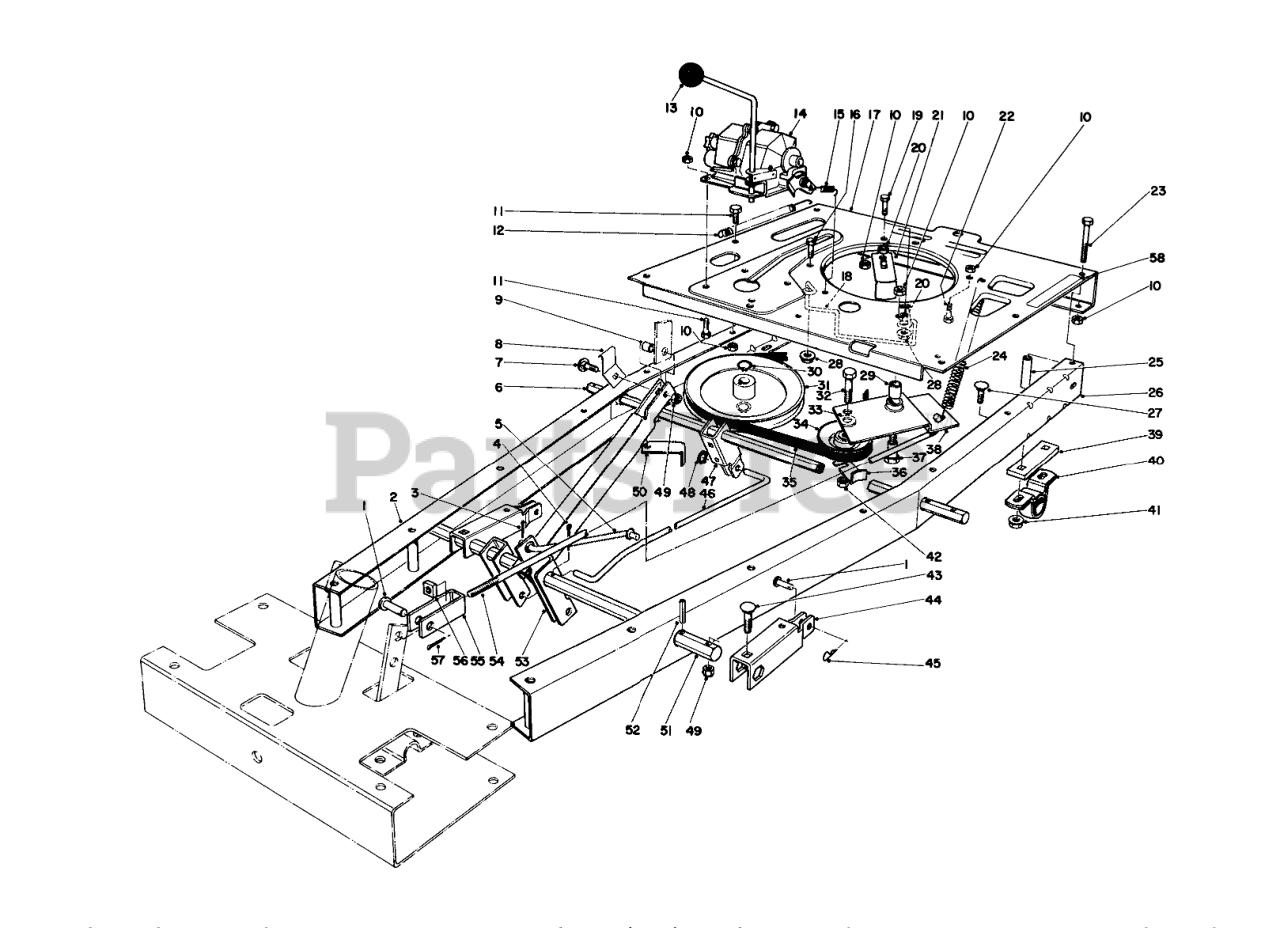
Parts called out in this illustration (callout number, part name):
1	PIN-CLEVIS
2	Frame Channel R.H.
3	PIN-COTTER
3	Cotter Pin
4	PIN-COTTER
5	Deck Engagement Rod
6	Hex Shaft-Rear Lift
7	SCREW-CARR
8	Flat Spring
9	Spacer
10	NUT-LOCK, CONE
11	SCREW-HH
12	Spring Tension Brake
13	KNOB-CONTROL
14	Transmission
15	Spring Tension Brake Return
16	SCREW-HH
17	Plate-Engine Mounting
18	Belt Guide
19	SCREW-HH
19	NUT-HEX
20	NUT-HEX
20	Belt Retainer
21	Belt Retainer
21	SCREW-HH
22	SCREW-HH
22	Spacer
23	SCREW-HH
24	SPRING-EXTENSION
25	Spacer-Split Tube
26	Channel Frame L.H.
27	BOLT-CARR
28	NUT-HF
29	BUSHING
30	RING-SNAP, EXTERNAL
31	Pulley
32	SCREW-HH
33	Washer
34	PULLEY-IDLER
35	TRACT DRIVE V-BELT
36	RETAINER-BELT
37	CLUTCH PIVOT BOLT
38	Tractor Idler Assembly (Incl. Ref. #29)
39	Spacer Pillow Block
40	PILLOW BLOCK
41	NUT-HF
42	NUT-LOCK, CONE
43	SCREW-CARR
44	Deck Lift Arm
45	PIN-COTTER, HAIR
46	Lift Transfer Rod
47	Lift Arm Transfer
48	Grip Ring
50	TRANS BELT RET B
51	Front Lift
52	PIN-SPRING
53	Arm Lever
54	Rod Clutch
55	Clevis Brake
56	NUT-SQUARE
57	PIN-COTTER
58	Caution Decal
